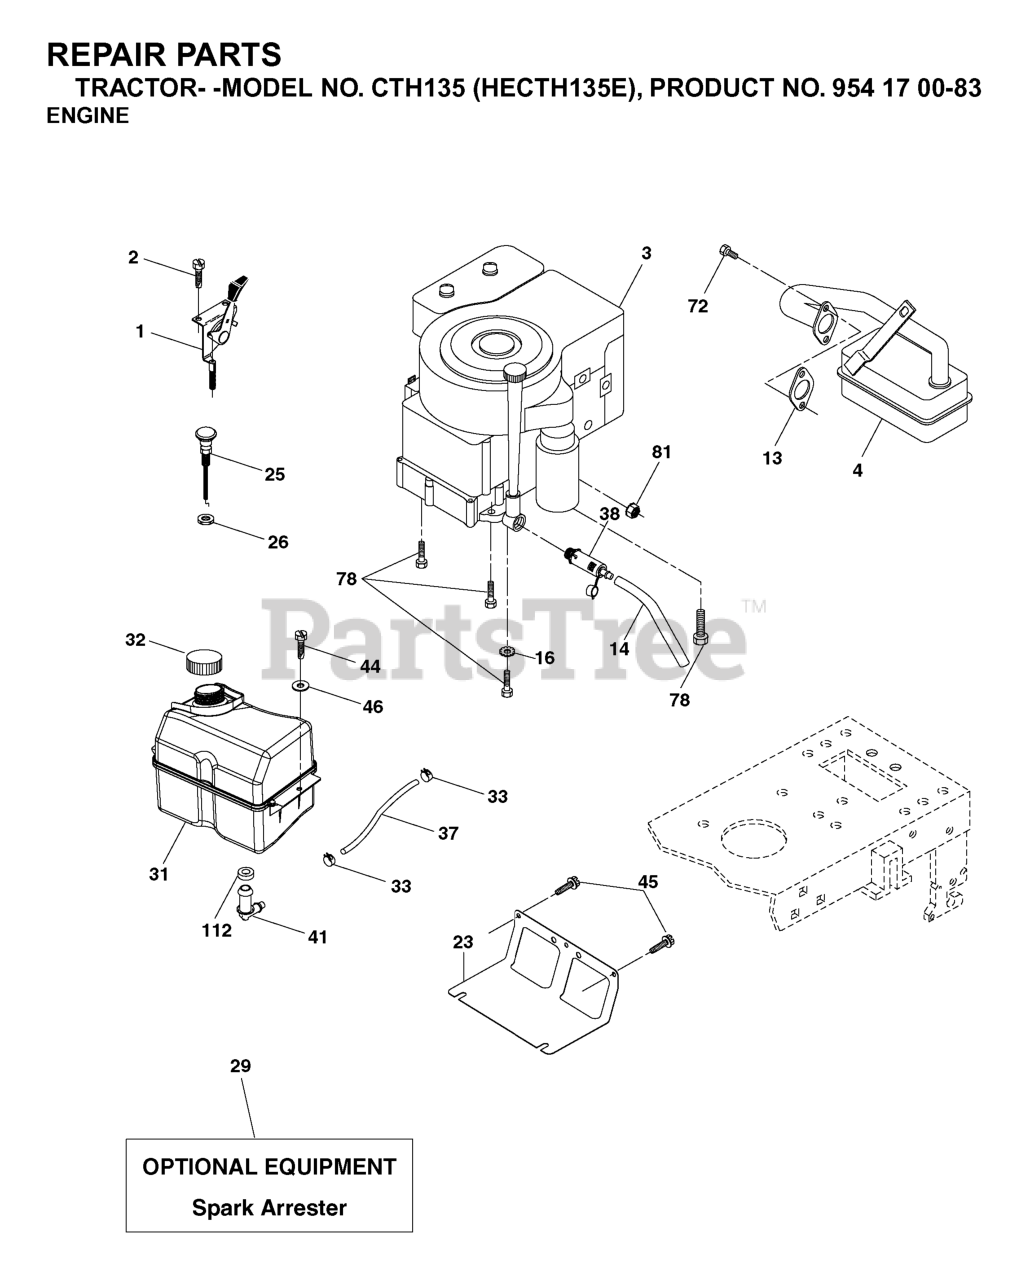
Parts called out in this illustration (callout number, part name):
1	CONTROL.THROTTLE/CHOKE.BLACK
2	SCREW
4	MUFFLER.LT.BRIGGS.14HP.IC/OHV
13	REPL BY 532 27 22-93
14	TUBE, DRAIN OIL ASM.
16	LOCKWASHER
23	SHIELD.BROWNING.DBR.GUARD
26	Nut Keps 3/8 - 24 UNF
29	KIT.SPARK ARRESTOR 794945 B&S
31	TANK FUEL
32	FUEL CAP
33	HOSE CLAMP
37	LINE.FUEL.20
38	PLUG DRAIN OIL EASY
41	STEM FUEL TANK
44	SCREW HEXWSHR 1/4-20X3/4
45	SCREW, 3/8-16X3/4
46	WASHER
62	WASHER.LOCK.HVY.HLCL.SPR.5/16
72	SCREW
78	SCREW.3/8-16
81	NUT
112	BUSHING OUTLET T
